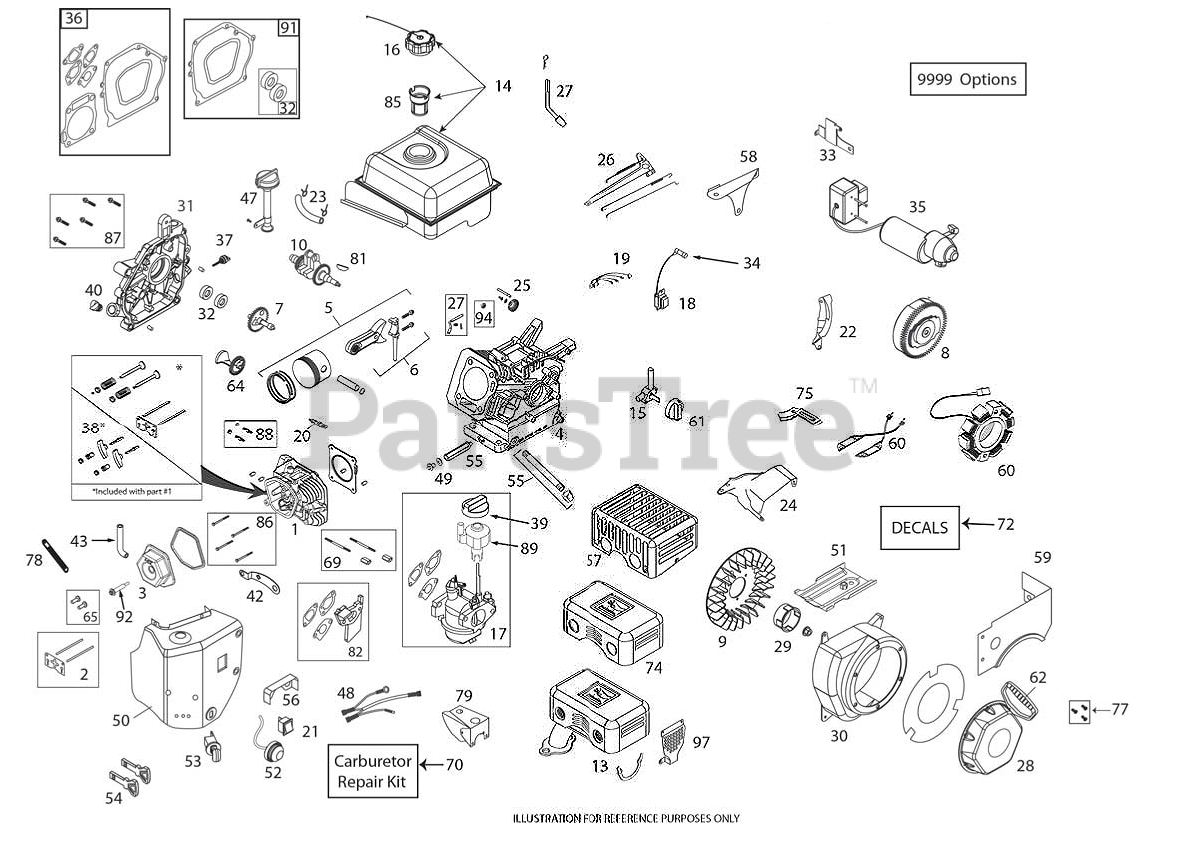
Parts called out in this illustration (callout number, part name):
1	CYLINDER HEAD LCT 178 INCLUDES
2	PUSH ROD TAPPET KIT
3	VALVE.COVER.LCT.414CC.
4	CYLINDER LCT 369 SKSN3333.1
5	PISTON.AND.ROD.ASSY(SK4141400)
5	PISTON ROD ASM.LCT SK3691400.1
6	CONNECTING ROD ASSEMBLY
7	CAMSHAFT(SK4141600)
8	FLYWHEEL.EL.ST.SKSN4408.1
9	FLYWHEEL.FAN(SK4144000)
10	CRANKSHAFT KEYED #18 LCT 414C
13	MUFFLER ASSY LCT SNO
13	MUFFLER.ASSY.SNOW(SKSN4200)
14	FUEL.TANK.ASSY.SNOW(SKSN4300)
15	FUEL.PETCOCK.SNOW(SKSN4900)
16	FUEL.TANK.CAP.SNOW(SKSN4301)
17	CARBURETTOR L18D LCT 369
18	IGNITION.COIL.(CDI).291-414CC
20	SPARK.PLUG(2083810)
20	SPARK.PLUG(SK2911550)
21	ON/OFF.SWITCH.SNOW(SKSN4403)
22	SHIELD.U/FYWHL.CHARG(SKSN4604)
23	FUEL HOSE KIT
24	RP TOP SHIELD
24	CONTROL.SPEED.FIXED.LCT.SKSN44
25	GOVERNOR.GEAR.ASSY(SK4142900)
26	GOVERNOR.ARM.ASSY(SKSN4502)
27	GOVERNOR.SHAFT(SK4143100)
28	RECOIL.START.ASSY.SNW(SKSN4600
28	RECOIL
29	STARTER.CUP.SML.SNOW(SKSN4601)
29	STARTER CUP
30	BLOWER HOUSING.LCT 369 GLOSS
30	BLOWER LCT 414CC
31	CRANKCASE.COVER.LCT.414CC.HIGH
32	OIL SEAL KIT NON-GENERATOR
33	ELECTRIC.START.BRKT(SKSN4405)
34	SPARK.PLUG.BOOT.SNW,SKSN4691.1
35	ELEC.START.ASSY.SNOW(SKSN4400)
35	STARTER EUROPEAN 230V ELECTRIC
36	GASKET KIT ENGINE LCT 369
37	DIPSTK.OIL.BLK.LCTSK4143711.1
38	ROCKER ARM KIT
39	CHOKE.KNOW.SNOW(SKSN4500)
40	NONREMVABLE.OIL.PLUG(SK4143715
42	CDI.BOX.BRKT.SNOW(SKSN4402)
43	BREATHER TUBE LCT 291/369/414
47	HIGHOIL.FILL.ASSY.KIT(SKSN4911
48	WIRE.HARNESS(SKSN4406)
48	WIRE.HARNESS.SNOW
49	OIL PIPE DRAIN EXTENDED.LCT SK
49	OIL.DRAIN.PLUG
50	HEATER.BOX.ASSY-SNW(SKSN4100)
51	SHIELD.CYLINDER.SNOW(SK4141010
52	PRIMER.BULB.ASSY(SKSN4304)
53	KEY.SWITCH.ASSY.SNOW(SKSN4401)
54	KEY SET(2 KEYS) SKSN0407.1
55	OIL PIPE DRAIN EXTENDED.LCT SK
56	SHIELD.VAPOR(SKSN4606)
57	CE COMPLIANT MUFFLER SHEILD
57	MUFFLER (SKSN2210.1)
58	PLATE.GOVERN.LINK.S
59	FUEL TANK SKIRT.LCT.369/420CC
59	SKIRT FUEL TANK
60	ALTERN.60WATT.SKSN2402.1
61	FUEL KNOB-SNOW
62	HANDLE.RECOIL.DELUXE.LCT
64	COUNTER WEIGHT KIT
65	TAPPET KIT.LCT.SK2911005.1
69	STUD.CARB.MOUTING.KIT.414CC
70	CARBURETTOR REPAIR KIT 291CC/4
72	ARIENS 414 SNOW DECAL KIT
74	MUFFLER SHIELD
77	BOLT.KIT.RECOIL.LCT.ALL.ENGINE
78	STRAP.RETAINING.TUBE.BREATHER.
79	SHIELD CARBURRETOR COVER 414
81	KEYS.FLYWHEEL.208/414CC.5PACK
82	SPACER.CARBURETOR.414CC.LCT
85	STRAINER.FUEL.TANK.LCT.208CC
86	KIT.BOLT.CYLINDER.HEAD.(4PC)
87	KIT.BOLT.CRANKCASE.COVER.414CC
88	STUD.MUFFLER.KIT.LCT
89	KNOB LCT.SKSN5325.1 SPEED
91	GASKET KIT CRANKSHAFT.LCT
92	CENTER VALVE COVER BOLT
94	Husqvarna TBD
94	SEAL GOVERNOR SHAFT OIL.LCT
97	GUARD.EXHAUST
9999	KIT.BOLT.LCT.SK9990.1
9999	STARTER SCREW.STARTER SWITCH B
9999	HIGH ALTITUDE JET 6000FT
